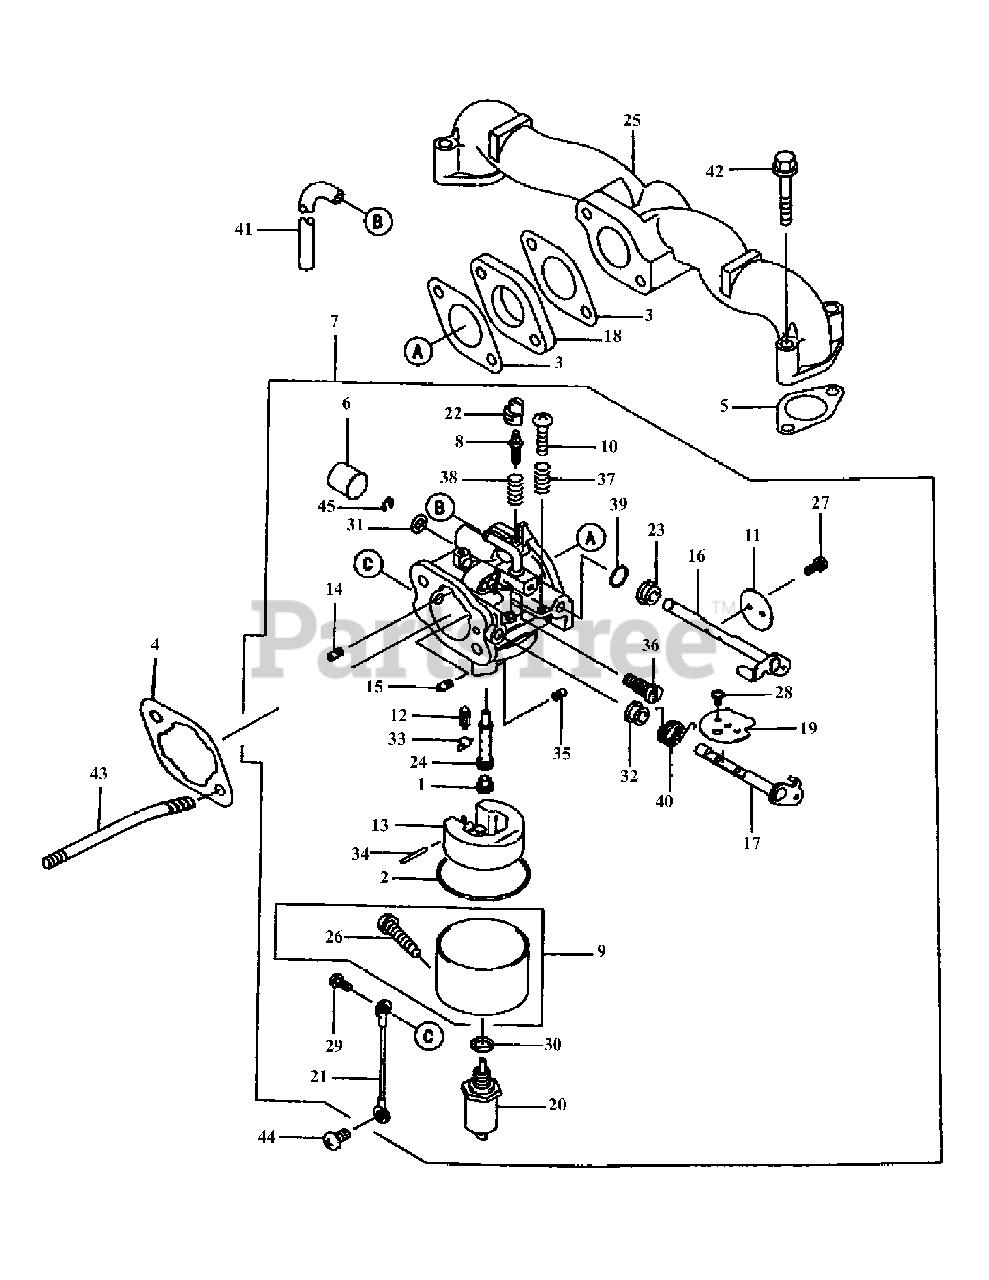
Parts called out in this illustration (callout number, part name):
3	Gasket, Insulator
4	Gasket, Air Filter
7	Carburetor, Assembly
8	Screw, Pilot Air
9	Chamber, Float
10	Screw, Throttle Stop
11	Valve, Throttle #135
14	Jet, Air #0.8
15	Jet, Air #2.0
16	Shaft, Carburetor, Throttle
17	Shaft, Carburetor
18	Insulator
23	Ring
24	Nozzle, Main #112B
25	Manifold, Intake
35	Jet, Main #106.3
36	Jet, Pilot #42.5
41	Tube, 4.76x7.94x225
42	Bolt, Flanged
45	Circlip, Type, E
